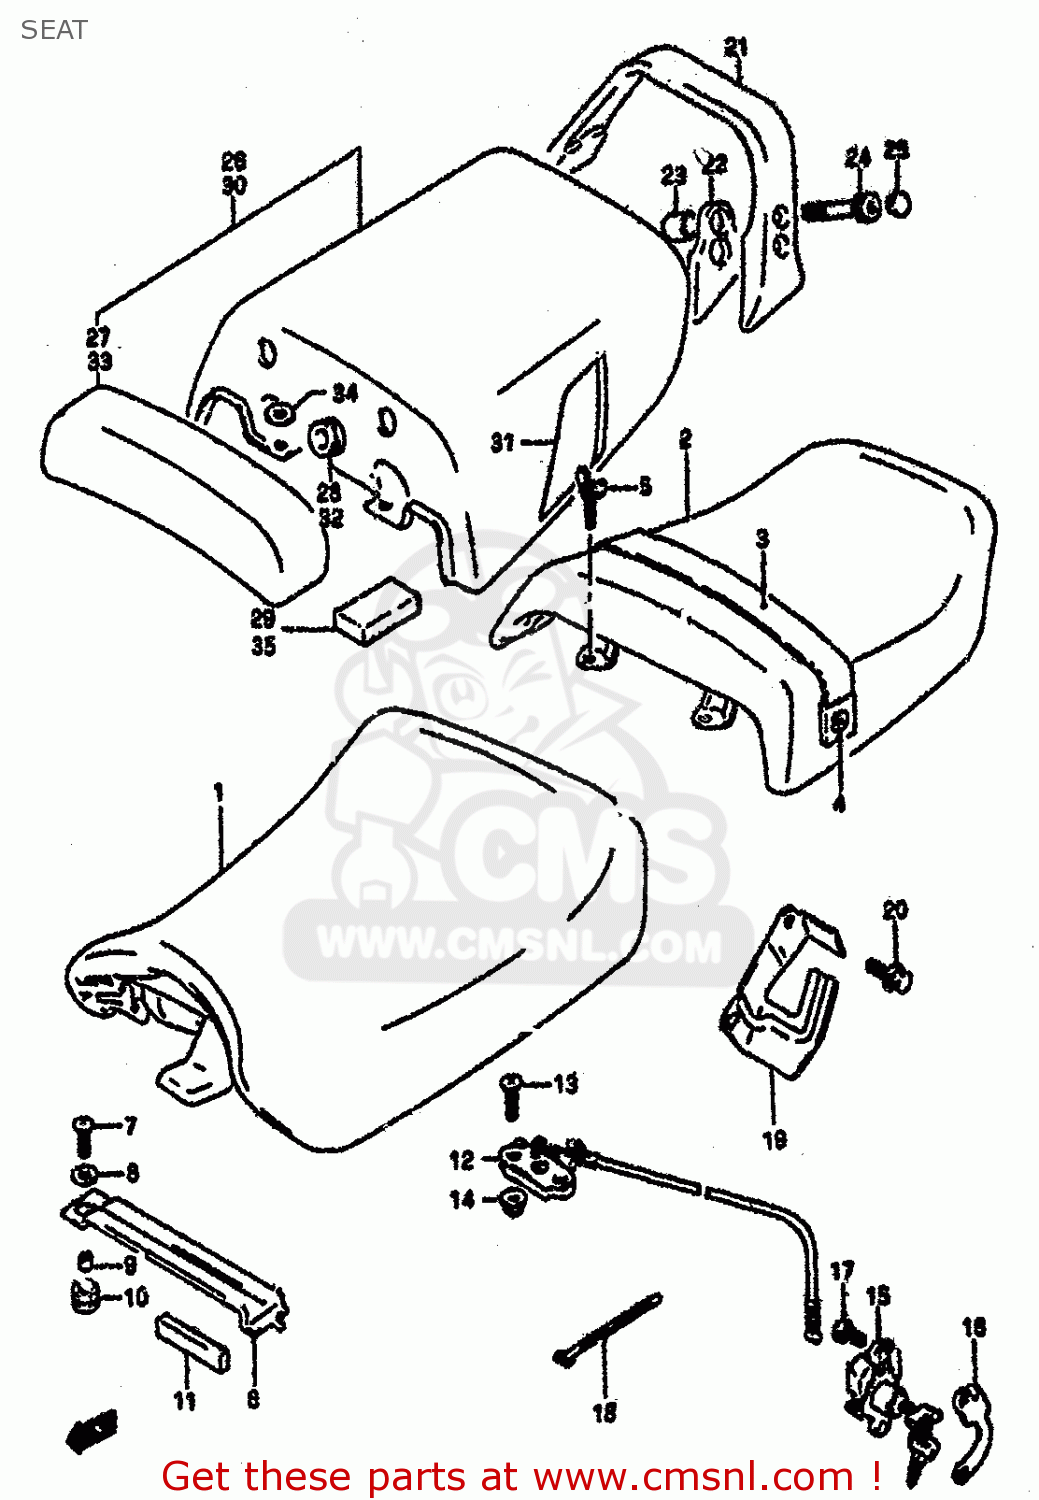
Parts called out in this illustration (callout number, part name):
1	SEAT ASSY
2	SEAT ASSEMBLY,PILLION
3	BAND COMP,SEAT
4	BOLT
5	SCREW(6X20)
6	PLATE,SEAT SUPPORT,REAR
7	SCREW, CENTER
8	WASHER
9	SPACER (6.1X8X9.5)
10	CUSHION
11	CUSHION,PLATE SEAT SUPPORT
12	BRACKET,SEAT SUPPORT RR
13	SCREW
14	NUT
15	LOCK SET,SEAT
16	PLATE,SEAT LOCK
17	SCREW(6X12)
18	CLAMP
19	PLATE,SEAT LOCK CABLE
20	BOLT
21	HANDLE,PILLION RIDER
22	CUSHION,PILLION RIDER
23	SPACER
24	BOLT
25	CAP(OD:14.5)
26	COVER SET,SINGLE SEAT
27	BACKREST,SEAT(BLACK)
28	CUSHION
29	MUD GUARD,REAR FENDER
30	BOX, SEAT TAIL (BLACK)
31	TAPE SET,SEAT TAIL BOX
32	CUSHION
33	BACKREST,SEAT(BLACK)
34	WASHER
35	MUD GUARD,REAR FENDER
